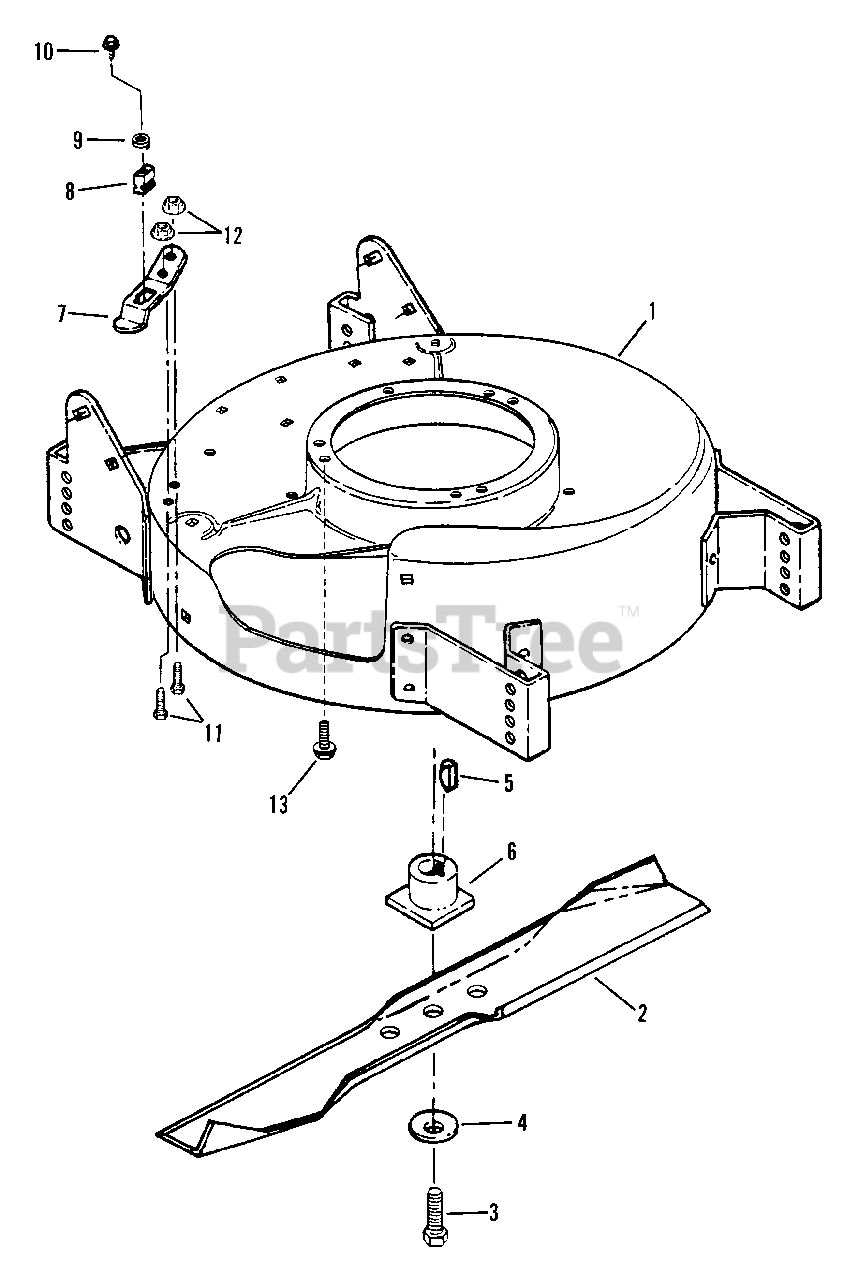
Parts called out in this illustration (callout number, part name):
1	DECK, Mower
2	BLADE, Cutter
3	SCREW, 3/8-24 x 2" Hex Head Cap (Gr. 5)
4	WASHER, Cone
5	KEY, Hi-Pro
6	HUB, Blade Drive
7	SPRING, Interlock
8	INSULATOR, Interlock
9	WASHER, #8 Tab
10	SCREW, #8-18 x 3/4" Self-Tapping
11	SCREW, 1/4-20 x 3/4" Hex Head Cap
12	NUT, 1/4-20 Hex Flange
13	SCREW, 3/8-16 x 1" Self-Tapping
